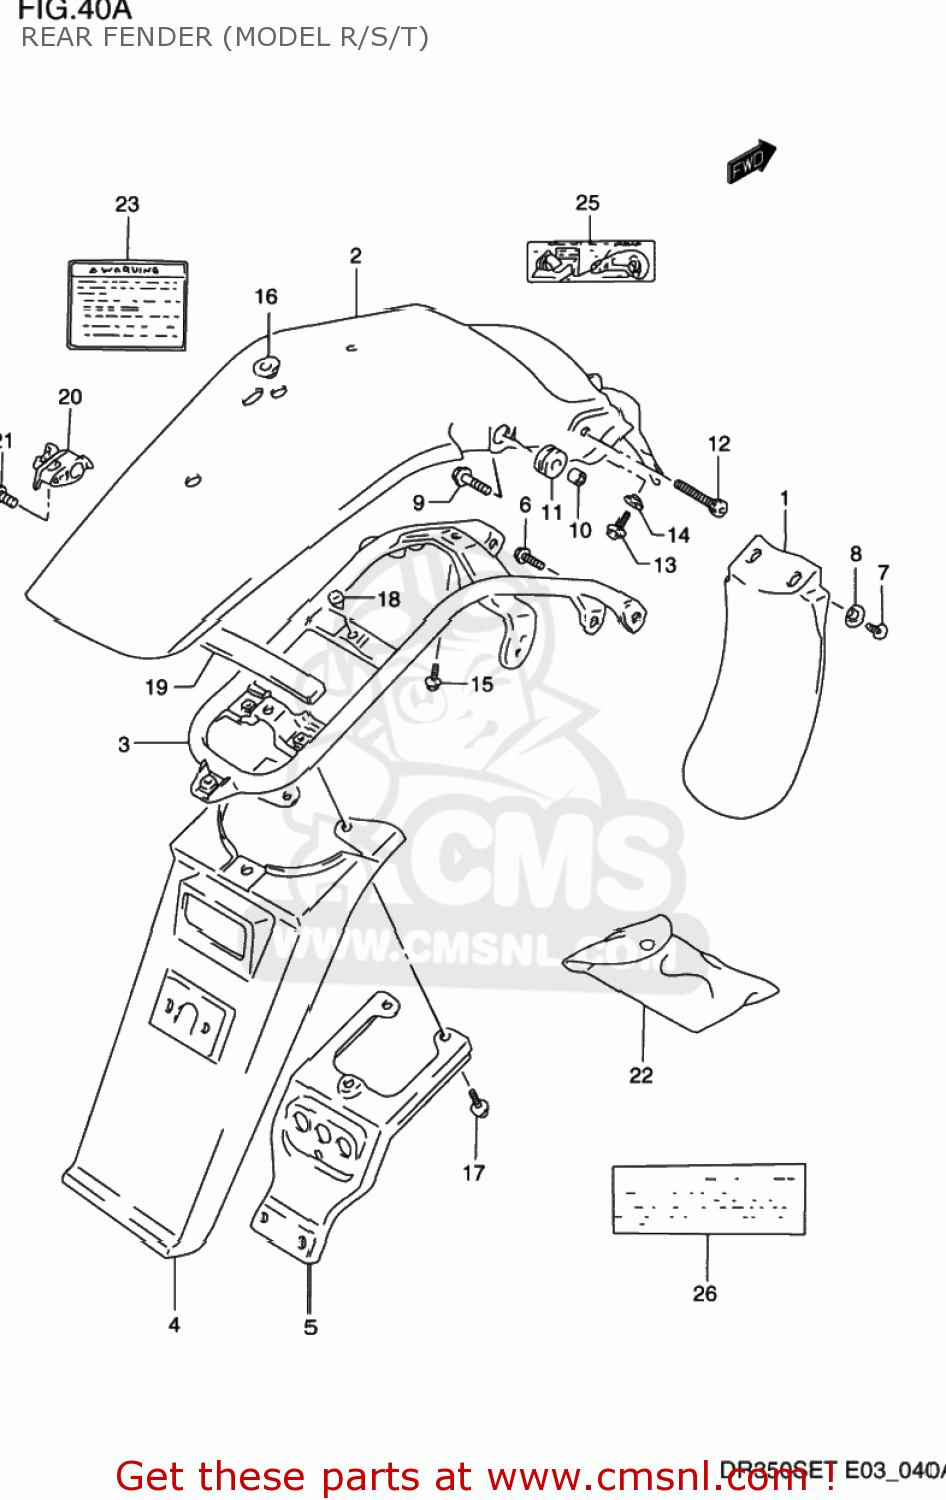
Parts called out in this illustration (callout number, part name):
1	BODY,RR FENDER FR
2	BODY,RR FENDER RR
3	REINF,RR FENDER
4	EXTENSION,RR FENDER
5	REINFORCEMENT,RR FENDER EXT
6	BOLT
7	SCREW 6X12
8	WASHER
9	BOLT(8X30)
10	SPACER (8.8X12X7)
11	CUSHION
12	BOLT(8X30)
13	BOLT
14	WASHER
15	BOLT
16	WASHER(14.2X26X1.2)
17	BOLT
18	CUSHION
19	CUSHION(25X185X15)
20	LOCK SET,HELMET
21	SCREW
22	TOOL ASSY
23	LABEL
24	LABEL (TIRE AIR PRESSURE)
25	LABEL,PIPING DIAG
26	LABEL (MANUAL NOTICE)
